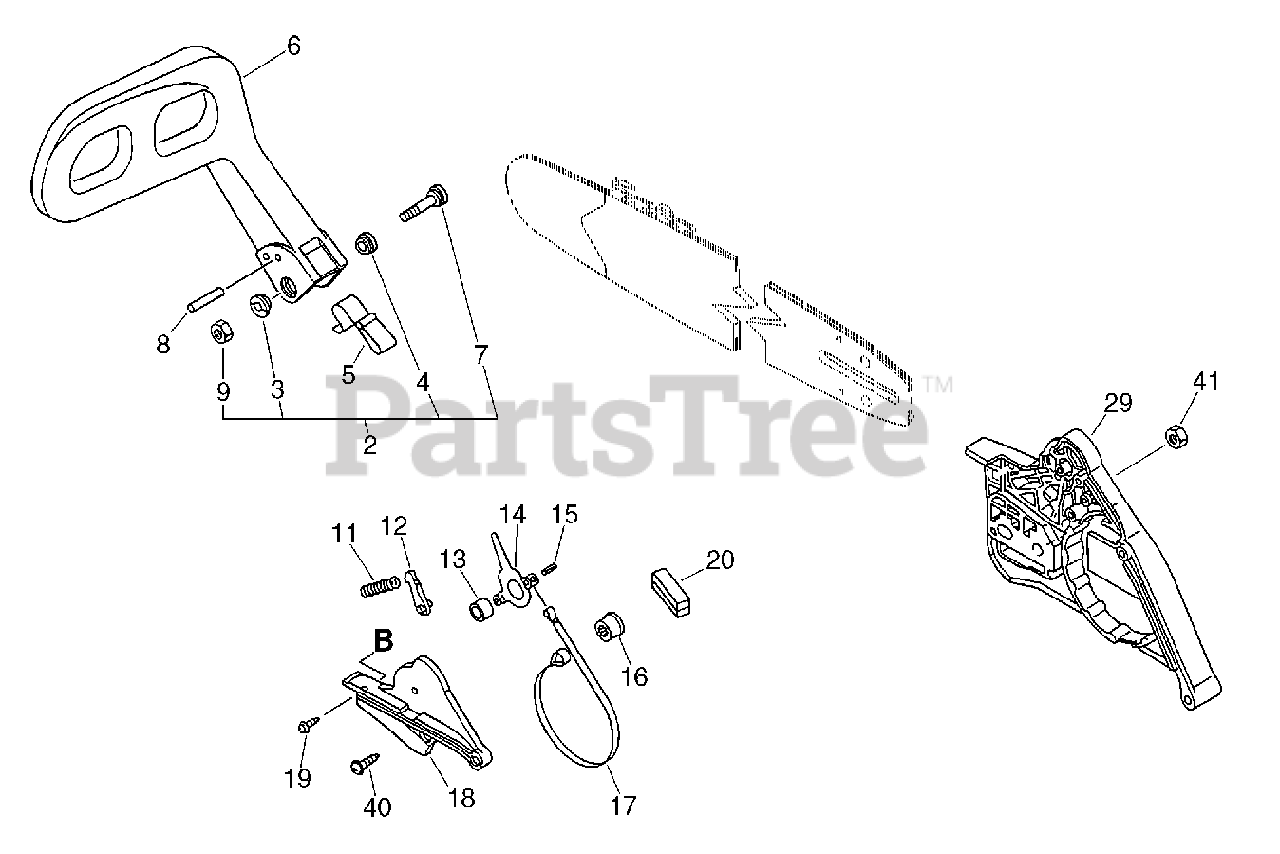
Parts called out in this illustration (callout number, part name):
2	MOUNTING KIT
3	COLLAR 5.3×10×13×L5
4	COLLAR 5
5	SPRING, FLAT
6	LEVER, BRAKE
7	SCREW 5×35
8	PIN 3.5×26
9	NUT, LOCK M5
11	SPRING, BRAKE
12	STOPPER, BRAKE
13	SPACER 8×12×9
14	LEVER, BRAKE
15	PIN, SPRING 4×8.8
16	ADJUSTER, BRAKE
17	BAND, BRAKE
18	COVER, BRAKE
19	SCREW 4×12
20	SEAL, BRAKE
29	GUARD, SPROCKET
40	SCREW 3×18
41	NUT 3 MM
